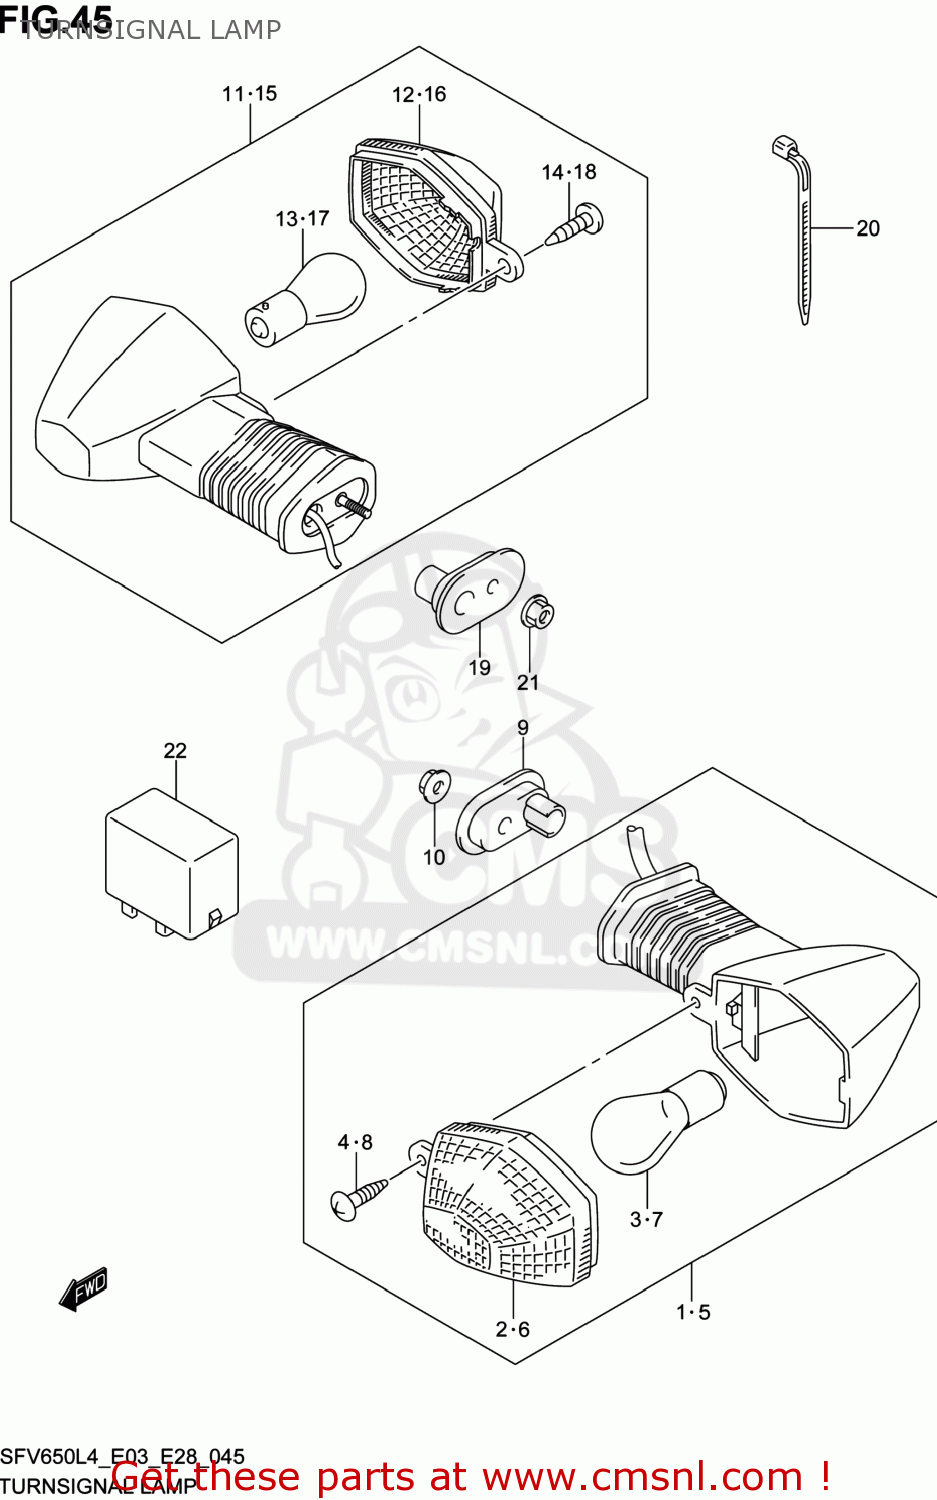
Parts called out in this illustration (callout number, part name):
1	LAMP ASSY,FR TURN SIGNAL,R
2	LENS
3	BULB(12V21W,AMBER)
4	SCREW
5	LAMP ASSY,FR TURN SIGNAL,L
6	LENS
7	BULB(12V21W,AMBER)
8	SCREW
9	PLATE,FR TURNSIGNAL
10	NUT
11	LAMP ASSY,RR TURNSIGNAL,R
12	LENS
13	BULB(12V21W,AMBER)
14	SCREW
15	LAMP ASSY,RR TURNSIGNAL,L
16	LENS
17	BULB(12V21W,AMBER)
18	SCREW
19	PLATE,FR TURNSIGNAL
20	CLAMP(L:165)
21	NUT
22	RELAY ASSY,TURNSIGNAL LAMP
